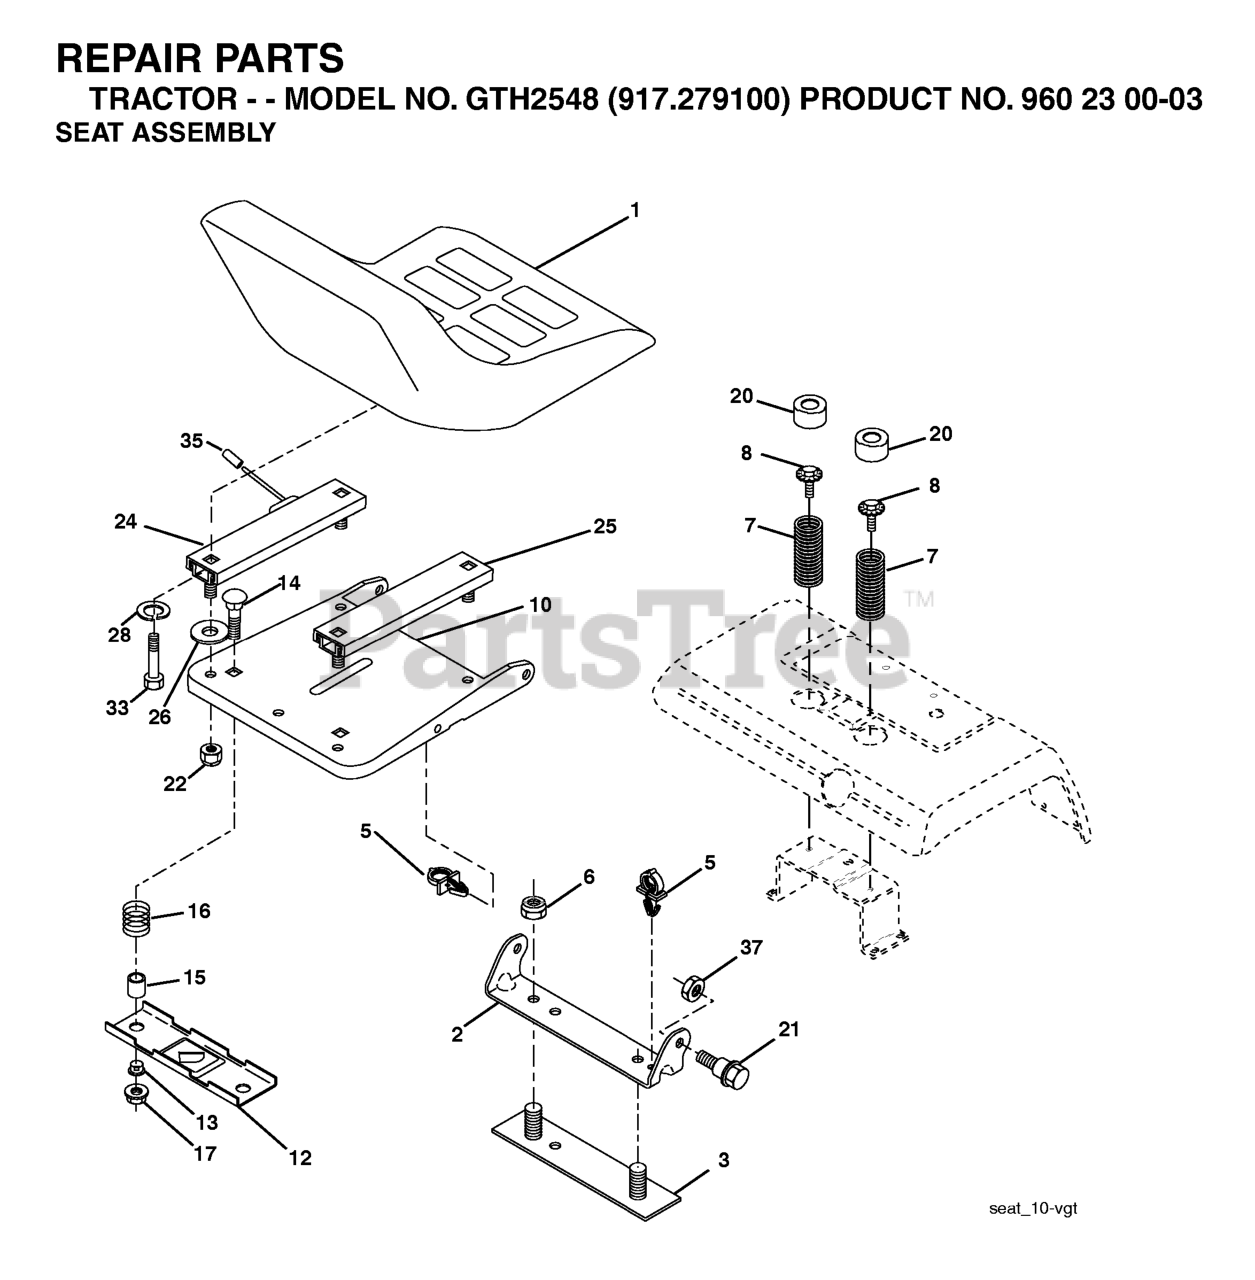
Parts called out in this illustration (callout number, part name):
1	SEAT.XH150.GRY
2	SEAT PIVOT BRKT
3	STRAP
6	NUT
7	SPRING COMPRESSION
8	BOLT.5/16-18UNCX3/4 W/SEMS.BLK
10	PAN SEAT
12	BRKT.MNTNG.SWITCH.SEAT.BLACK
14	BOLT.ROUND.HEAD.SQUARE.NECK
15	SPACER SPLIT
16	SPRING COMPRESSED
17	NUT T
20	CAP SPRING
21	BOLT.SHOULDER.5/16-18
22	LOCKNUT
24	TRACK SLIDE, SEAT(L)
25	TRACK SLIDE, SEAT(R)
33	BOLT.FIN.HEX.5/16-18X3/4
35	CAP
37	NUT.71038.31-18.HEX.NYLOCK
